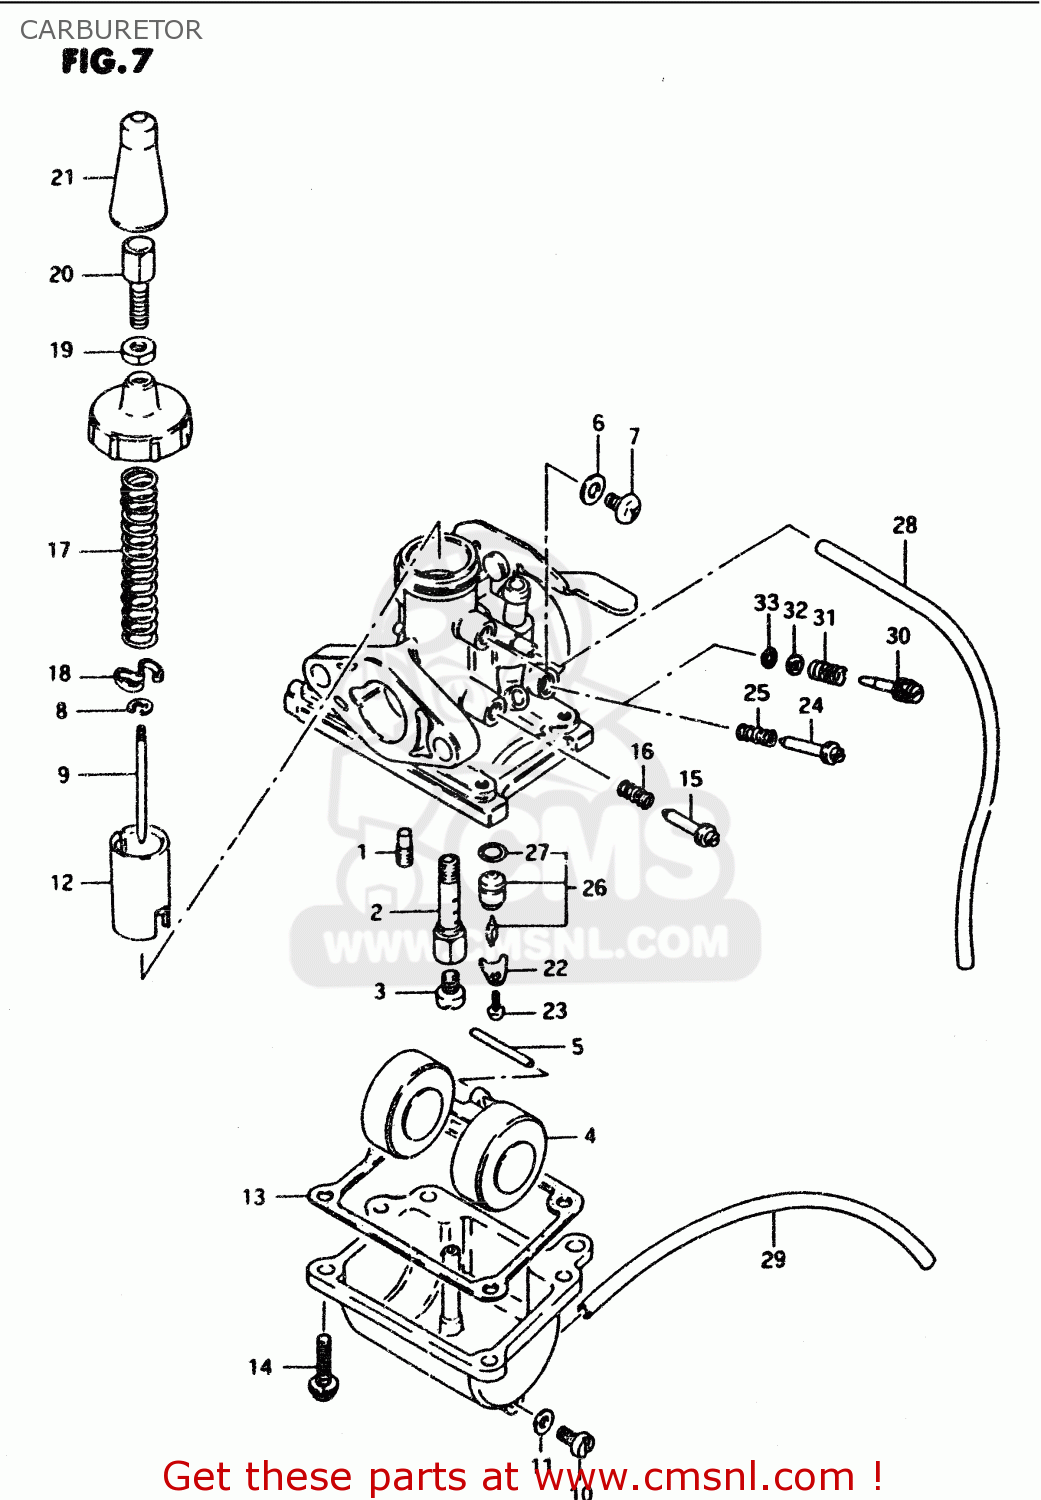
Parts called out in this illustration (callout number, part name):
1	JET,PILOT
2	JET, NEEDLE (E-7)
3	JET, MAIN (57.5)
4	FLOAT
5	PIN,FLOAT
6	GASKET,DRAIN PLUG (NAS)
7	SCREW
8	CLIP,NEEDLE
9	NEEDLE,JET
10	PLUG
11	GASKET,DRAIN,PLUG (NAS)
12	VALVE,THROTTLE
13	GASKET (NAS)
14	SCREW
15	SCREW,THROTTLE STOP
16	SPRING
17	SPRING,THROTTLE VALVE RETURN
18	PLATE
19	NUT
20	ADJUSTER,CABLE
21	CAP,CABLE ADJUSTER
22	PLATE,NEEDLE VALVE FITING
23	SCREW
24	SCREW,AIR
25	SPRING
26	VALVE ASSY,NEEDLE
27	O RING
28	HOSE
29	HOSE(3X5X650)
30	SCREW,AIR
31	SPRING
32	WASHER
33	O RING,PILOT AIR SCREW
